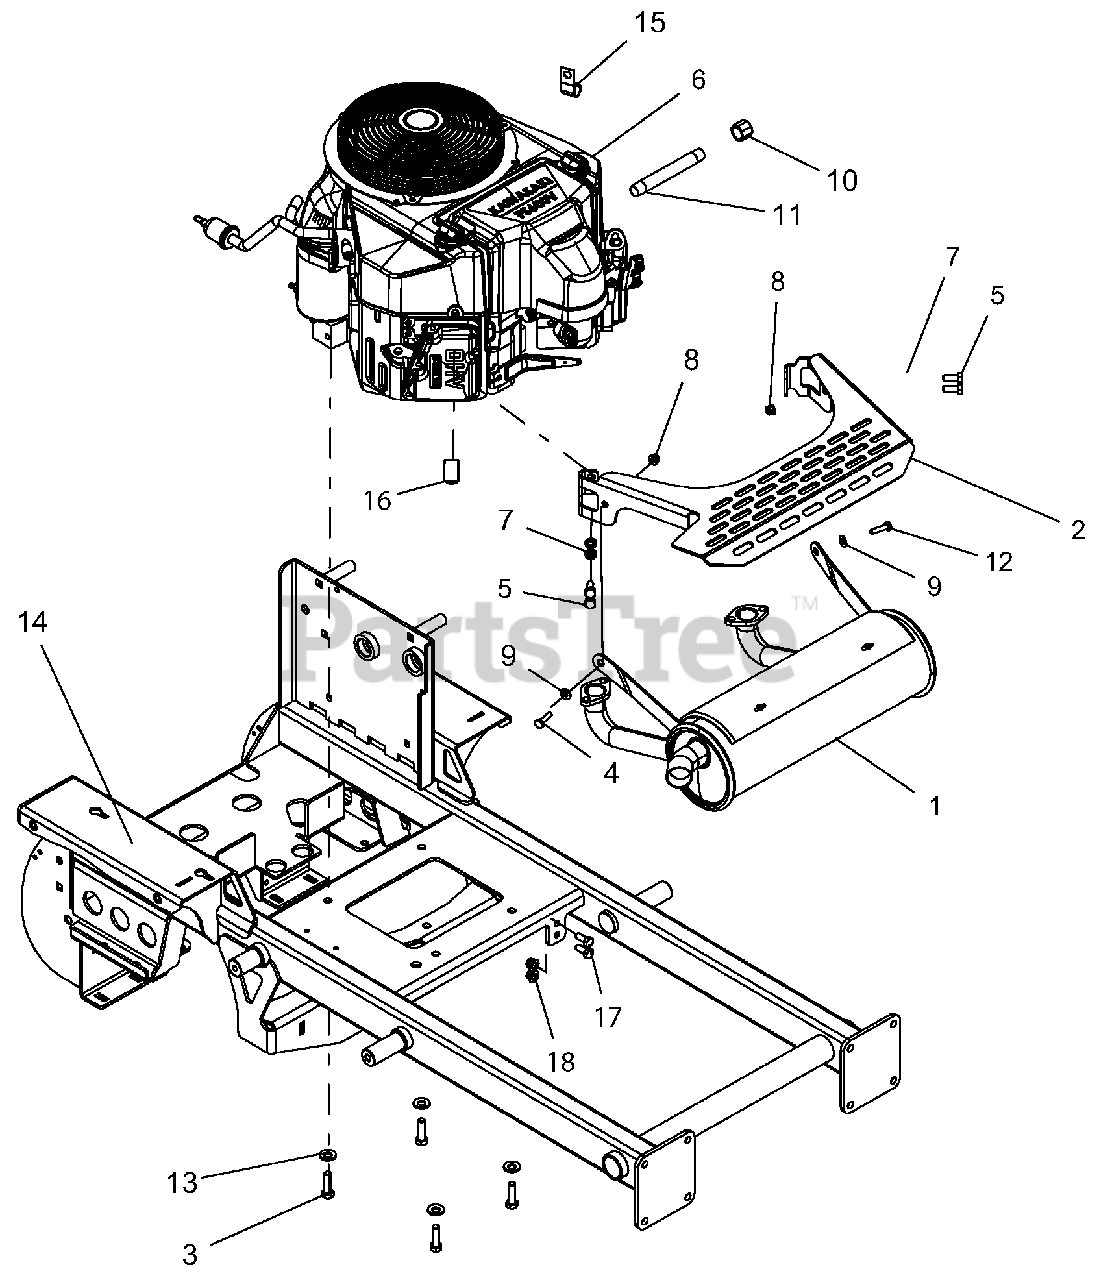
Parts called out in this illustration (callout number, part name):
1	EXHAUST, KAWASAKI FS
2	SHIELD, MUFFLER-BLACK
3	BLT-HEX .38-16X1.25 GR5 YWZC NYTORQ
4	BLT-HEX .25-20X1.00 GR5 YWZC
5	@BLT-HEX M8-1.25X20 YWZC
6	ENGINE, KAWASAKI FS600
7	WSHR-LK .31X.078 REG YWZC
8	NUT-LK-NYL-FLG .25-20 YWZC
9	WSHR-FL-STL.281X.62X.065 YWZC
10	PIPE, CAP 3/8 NPT FEMALE
11	PIPE, .375" NPT X 5"
12	BLT-HEX .25-20X1.00 GR5 YWZC
13	WSHR, 3/8" SPRING DISC
14	WLDMT, FRAME PROSTANCE
16	CLAMP, CUSHIONED STEEL REV
17	BLT-HEX .31-18X.75 GR5 YWZC
18	NUT-LK-NYL-FLG .31-18 YWZC
